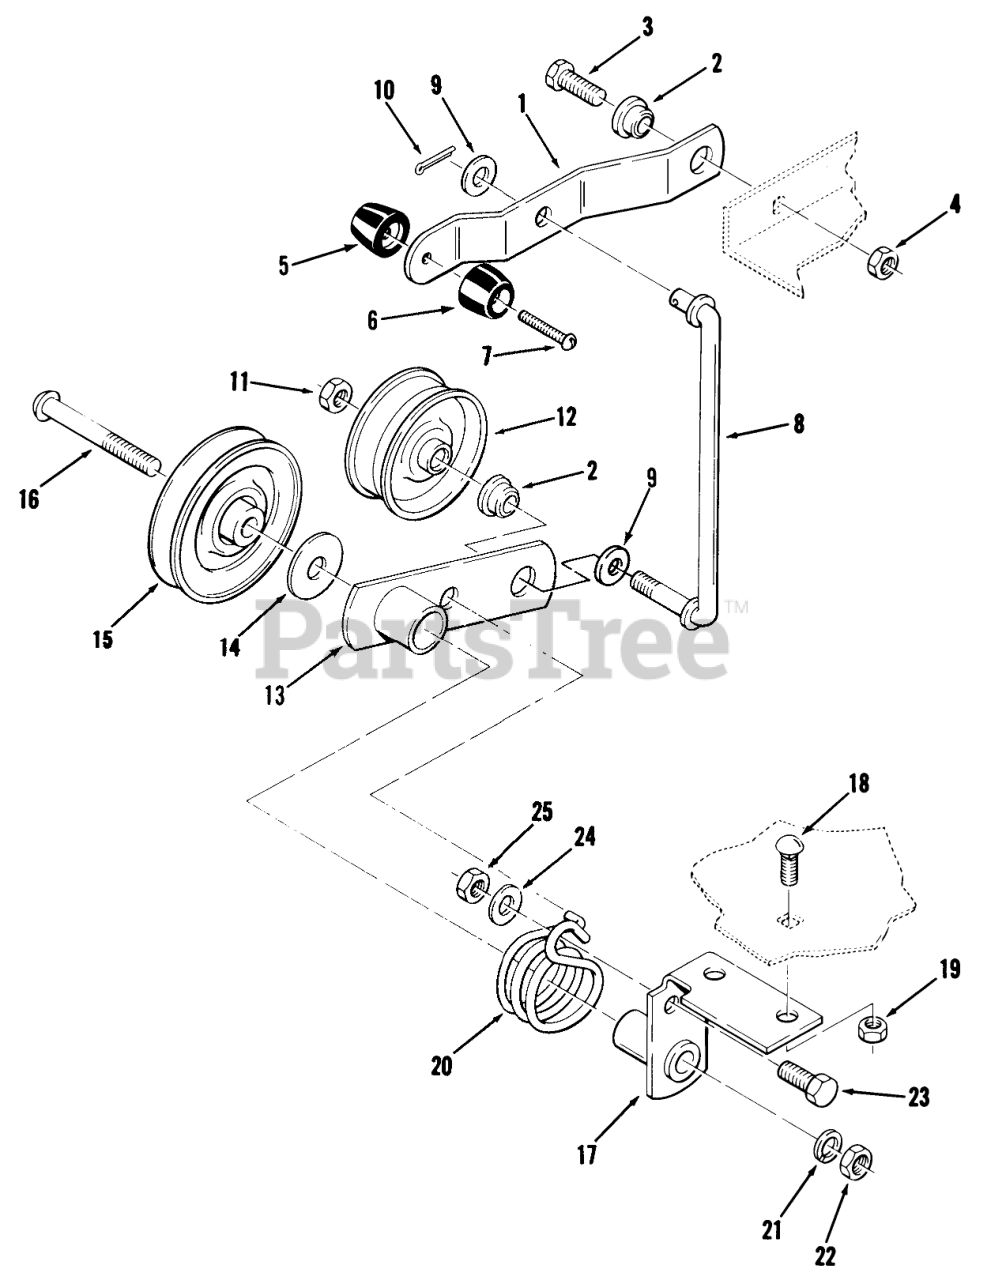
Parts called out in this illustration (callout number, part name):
1	LEVER
2	SPACER-BRAKE LINK
3	BOLT
4	Nut
5	KNOB
6	KNOB
7	BOLT-4
9	Washer
10	Pop Rivet
11	Nut
12	IDLER PULLEY
13	ASSY-IDLER ARM
14	WASHER
15	PULLEY-IDLER
16	SCREW 3/8-16X23/4
17	Idler Arm Support
18	Bolt
19	Nut
20	SPRING-TORSION
21	LOCKWASHER
22	Nut
23	Bolt
24	Washer
25	Nut
